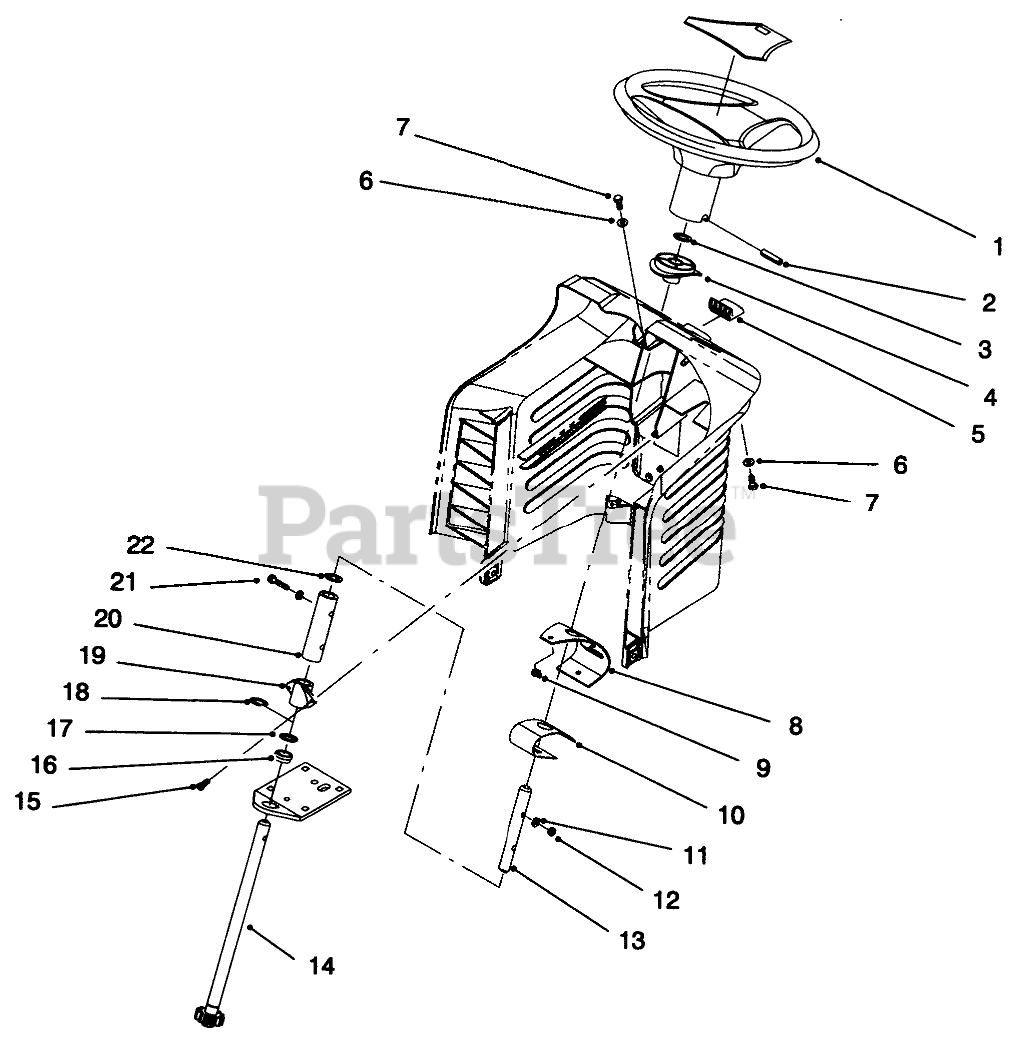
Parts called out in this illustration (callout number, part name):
1	Steering Wheel
1:2	COVER-WHEEL
2	PIN-ROLL
3	PUSH-ON RETAINING RING
4	BUSHING-SLIDING
5	RELEASE BUTTON
6	WASHER-FLAT
7	SCREW-HH
8	BACKUP BRACKET
9	NUT-LOCK, NI
10	SPRING LEAF
11	WASHER
12	NUT-LOCK, NI
13	UPPER STEERING SHAFT
14	SHORT STRG SHAFT WA
15	SCREW-SPECIAL
16	BEARING-FLANGE
17	WASHER-THRUST
18	E-RING
19	BUSHING STATIONARY
20	COUPLING, STEERING
21	SCREW-HH
22	WASHER-THRUST
